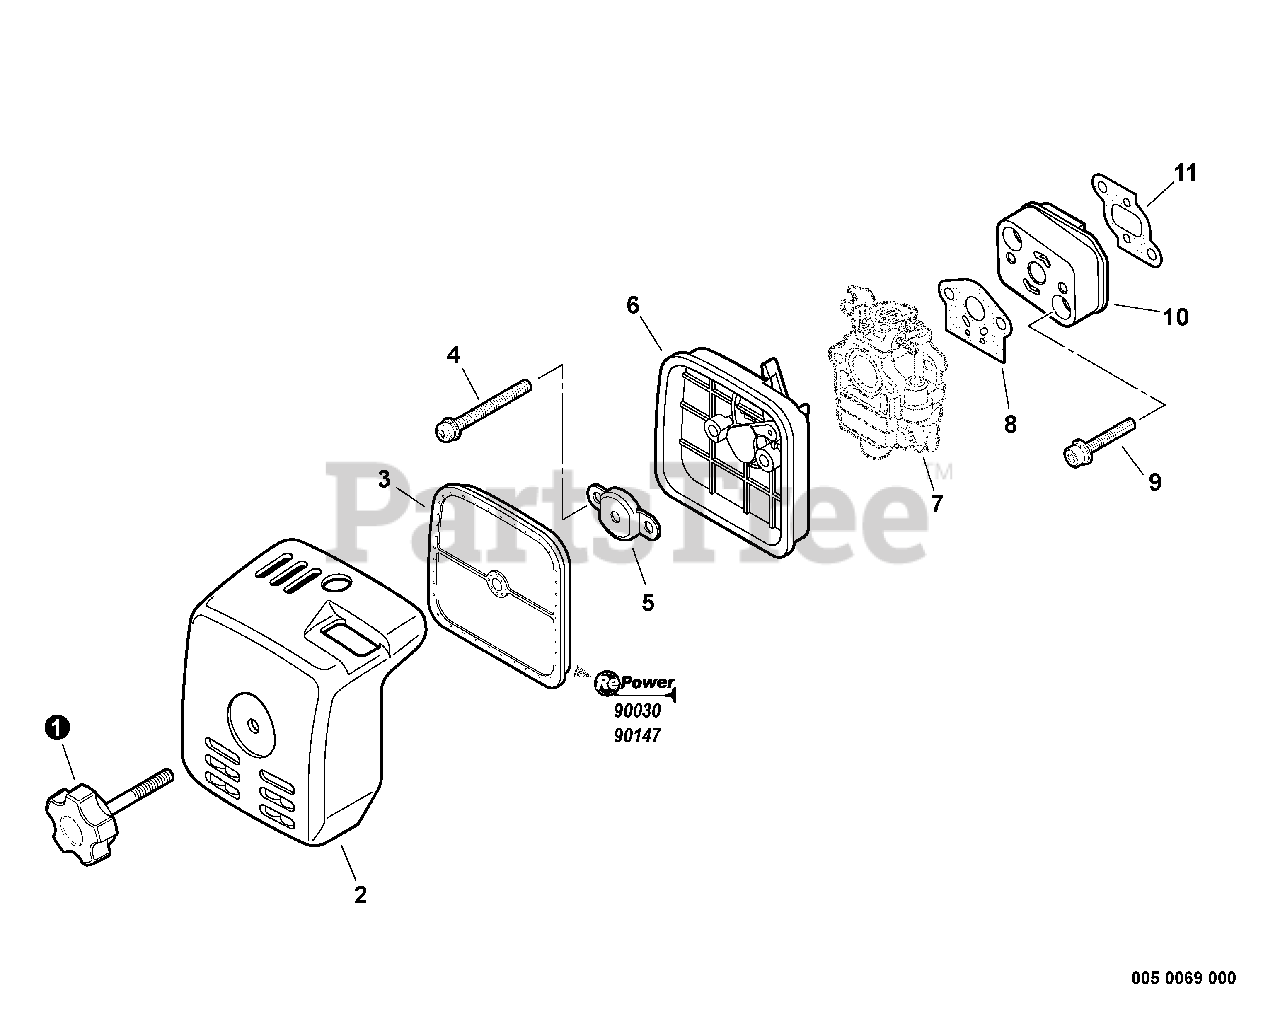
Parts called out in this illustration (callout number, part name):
1	THUMBSCREW
2	COVER, AIR FILTER
3	FILTER, AIR - HEAVY DUTY
4	SCREW - 5X60
5	PLATE, PREVENT
6	CASE, AIR FILTER
7	CARBURETOR
8	GASKET, INTAKE
9	SCREW - 5X25
10	INSULATOR, INTAKE
11	GASKET, INTAKE
12	RePower FILTER KIT
13	RePower TUNE-UP KIT
